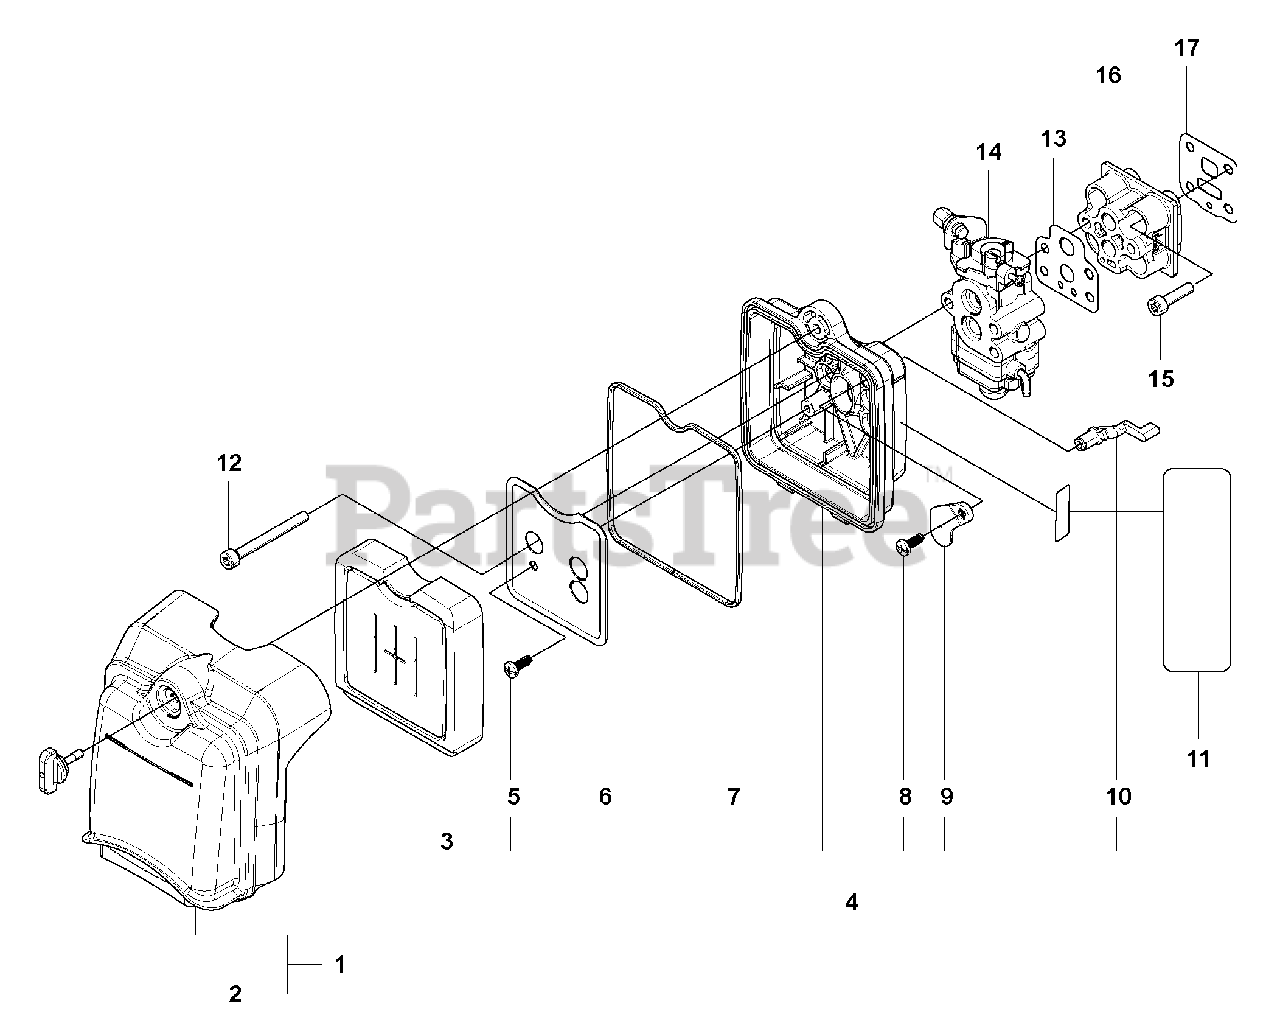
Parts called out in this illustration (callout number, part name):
1	COVER A
4	BODY AND SCREEN
5	BODY AND SCREEN
6	BODY AND SCREEN
7	BODY AND SCREEN
8	BODY AND SCREEN
9	BODY AND SCREEN
10	BODY AND SCREEN
11	LABEL, CHOKE
14	CARBURETOR A
15	BOLT
17	GASKET INSULATOR
